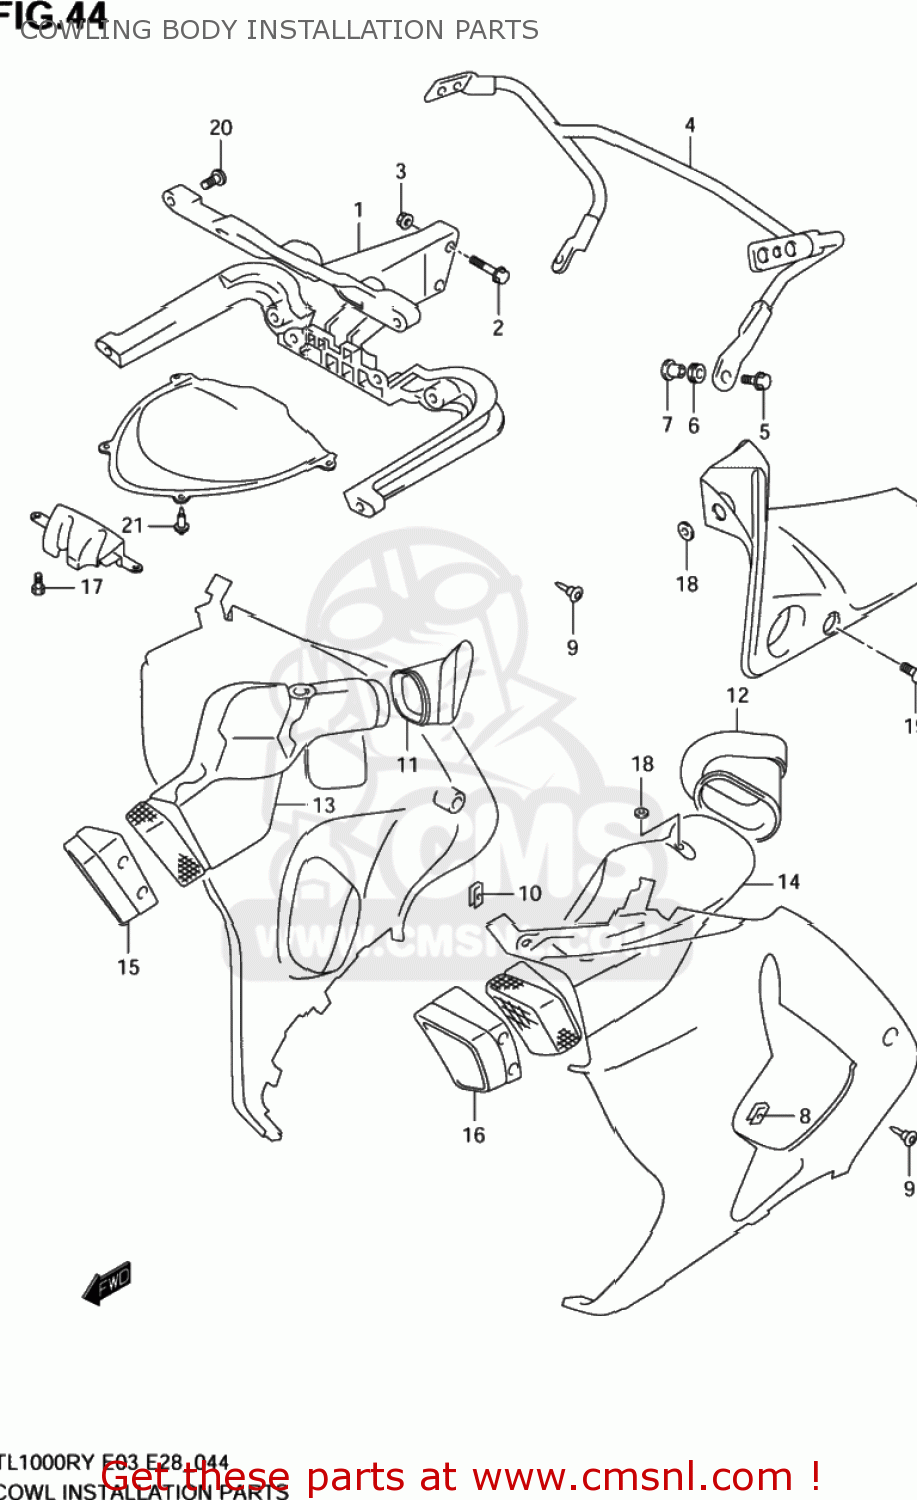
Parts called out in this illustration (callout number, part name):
1	BRACE,COWLING
2	BOLT
3	NUT
4	BRACE,RR VIEW MIRRORR
5	BOLT(6X25)
6	CUSHION
7	WASHER
8	NUT,COWL
9	SCREW(5X16)
10	NUT
11	JOINT,AIR INTAKE,RR,R
12	JOINT,AIR INTAKE,RR,L
13	PIPE,AIR INTAKE,R
14	PIPE,AIR INTAKE,L
15	COVER,INTAKE,R
16	COVER,INTAKE,L
17	BOLT
18	CUSHION
19	SCREW
20	SCREW
21	CLIP(BLACK)
